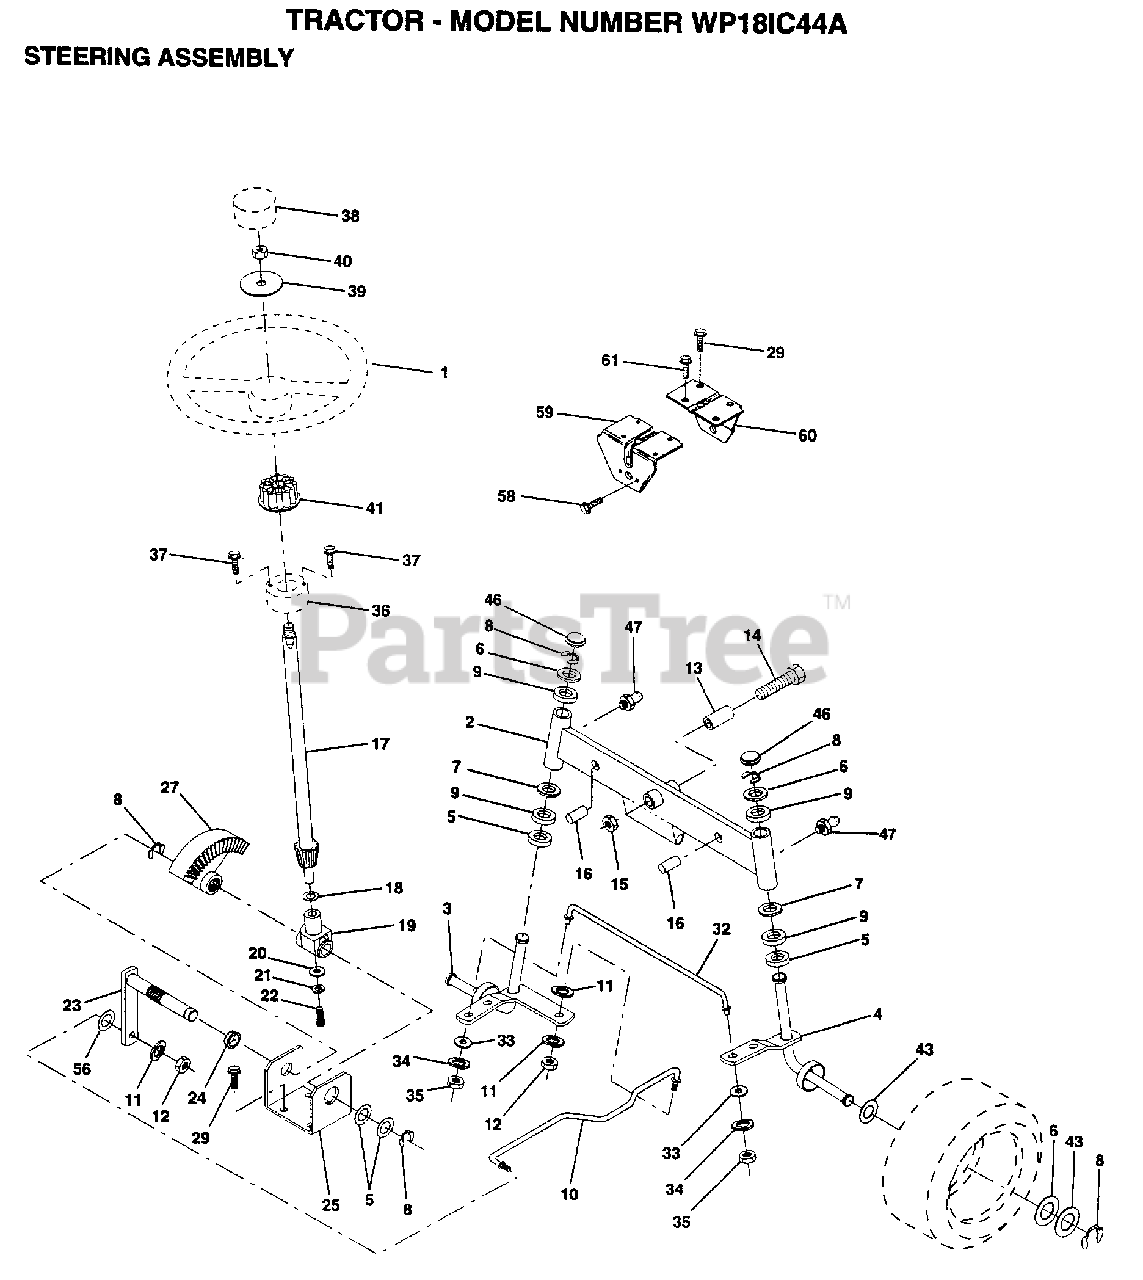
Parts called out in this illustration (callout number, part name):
2	AXLE ASM FRONT
5	WASHER .T
6	WASHER
7	WASHER
8	RING
9	COL. SRTG. BEAR.
11	LOCKWASHER
13	BEARING
14	BOLT LT
15	"NUT-LOC,FLANGE LT"
16	AXLE PIN
18	THRUST WASHER
19	SUPPORT.SHAFT
21	LOCKWASHER
22	"SCREW,SPECIAL"
24	NYLINER T
25	"BRKT,STEERING"
27	GEAR SECTOR
29	SCREW
32	TIE ROD
33	WASHER M
34	LOCKWASHER
35	NUT.LOCK.5/16-24
36	BUSHING.STRG.3/4
37	SCREW.10-24X1/2
38	"INSERT,STR WHEEL"
39	WASHER
41	ADAPTER LT
43	WASHER
46	CAP
47	ZERK M
56	WASHER
58	SCREW LT
59	SUPPORT-SADDL T
60	SUPPORT.SADDLE.FT
61	SCREW SPECIAL
